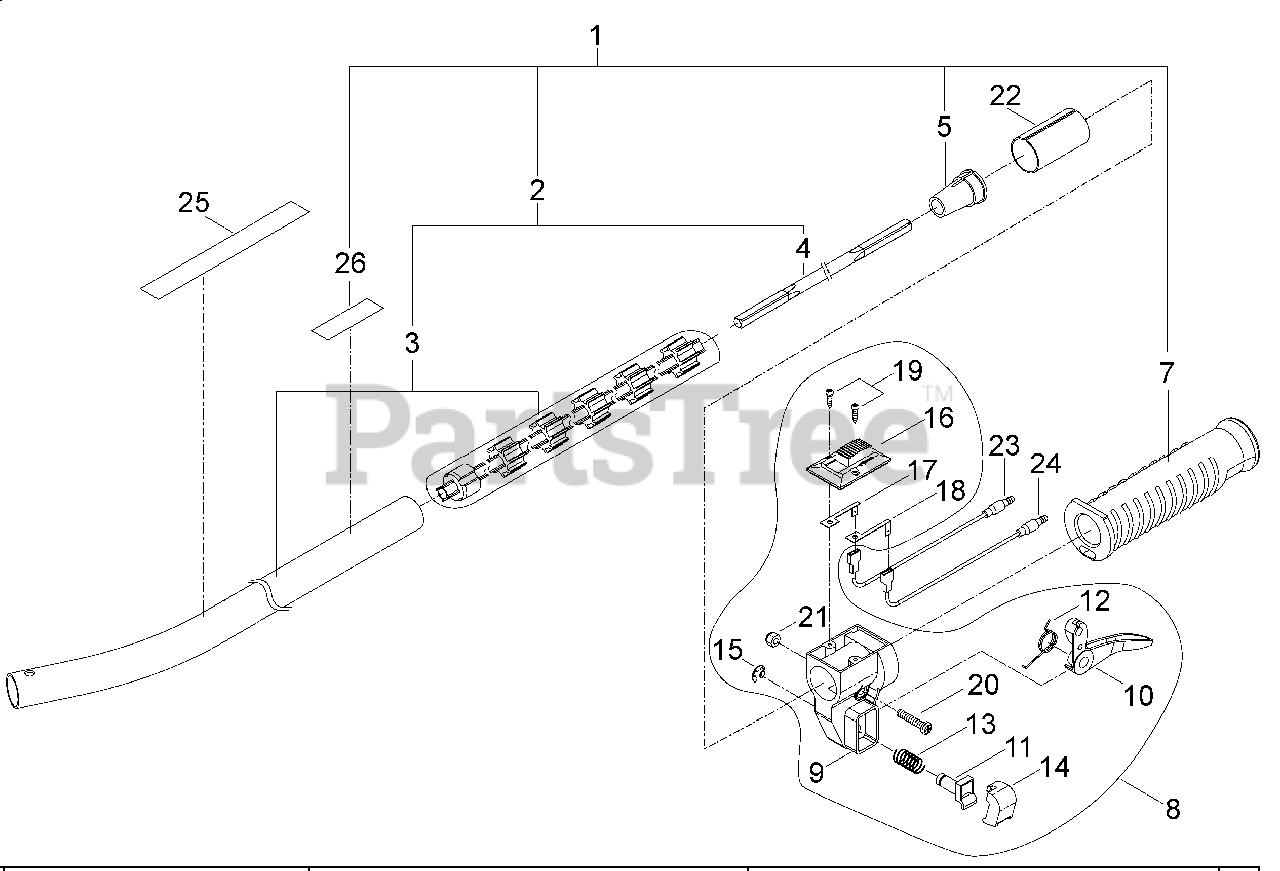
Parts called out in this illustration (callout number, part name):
1	MAIN PIPE ASSY
2	MAIN PIPE ASSY
3	PIPE - OUTER
4	FLEXIBLE SHAFT
5	SPACER
7	GRIP - REAR
8	THROTTLE LEVER ASSY
9	BODY
10	TRIGGER, THROTTLE
11	SHAFT
12	SPRING, TRIGGER
13	SPRING
14	BUTTON
15	RING, RETAINING
16	SWITCH ASSY
17	TERMINAL - GROUND
18	TERMINAL - GROUND
19	SCREW - TAPPING
20	SCREW - 5X20
21	NYLON NUT
22	SPACER
23	WIRE
24	WIRE
25	LABEL - TRADE
26	LABEL - CAUTION
